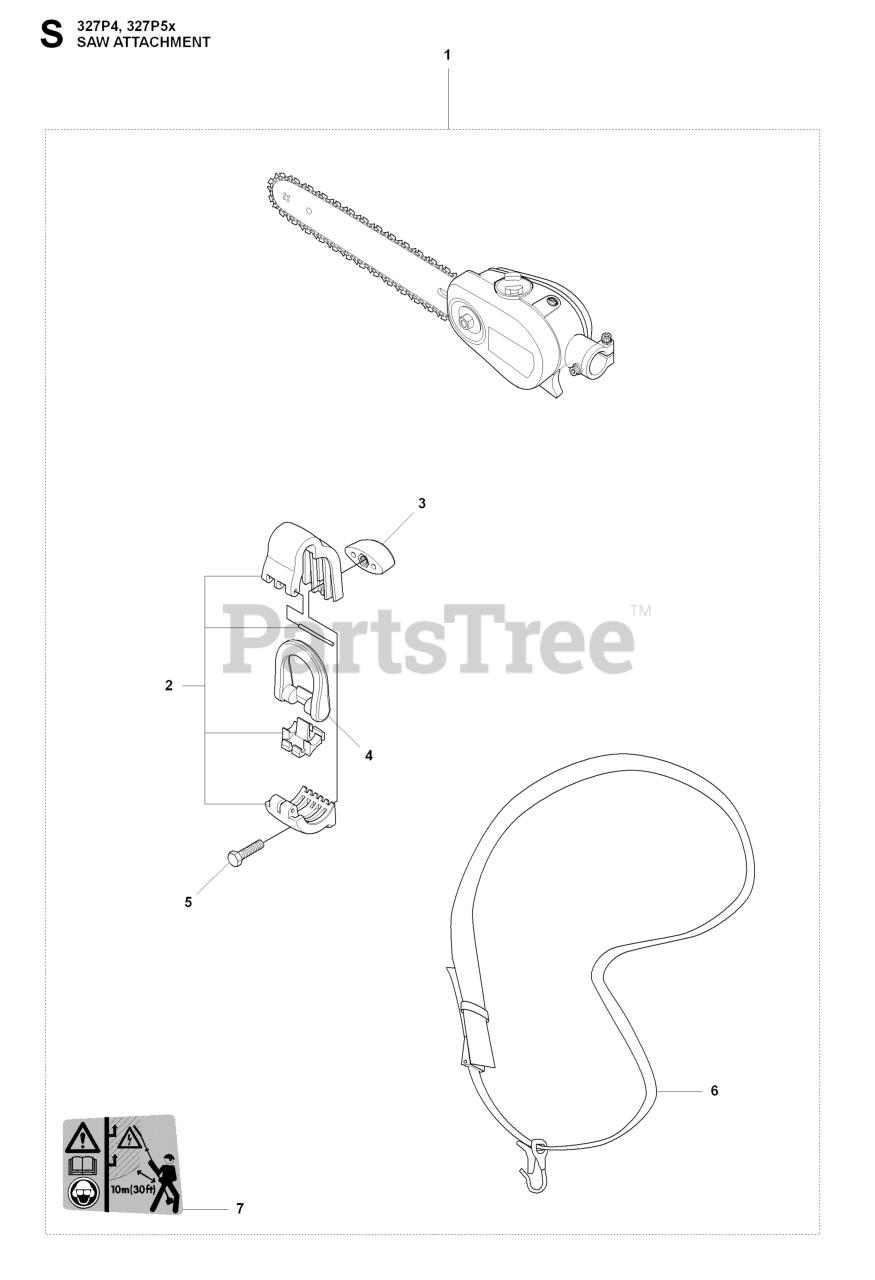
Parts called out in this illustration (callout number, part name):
1	Pole Saw Head W/12" Bar &
2	HANGING BRACKET
5	SCREW M6S 5X20
6	Harness-w/o warning
7	DECAL
